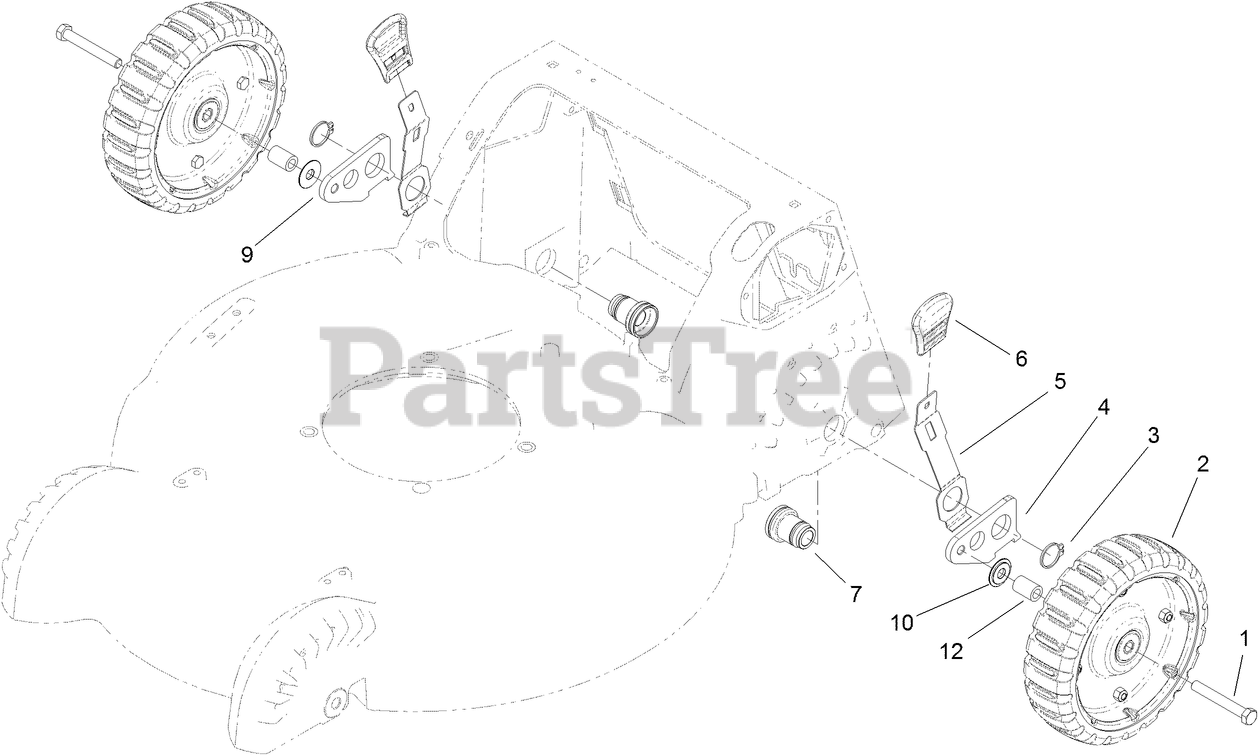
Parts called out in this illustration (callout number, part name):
1	SCREW-HH
2	8-INCH WHEEL ASM
3	RING-RETAINING
4	ARM-REAR PIVOT, LH
5	ARM-SPRING, REAR
6	KNOB-HOC
7	RETAINER-BEARING
9	ARM-REAR PIVOT, RH
10	WASHER-STEPPED
12	SPACER
